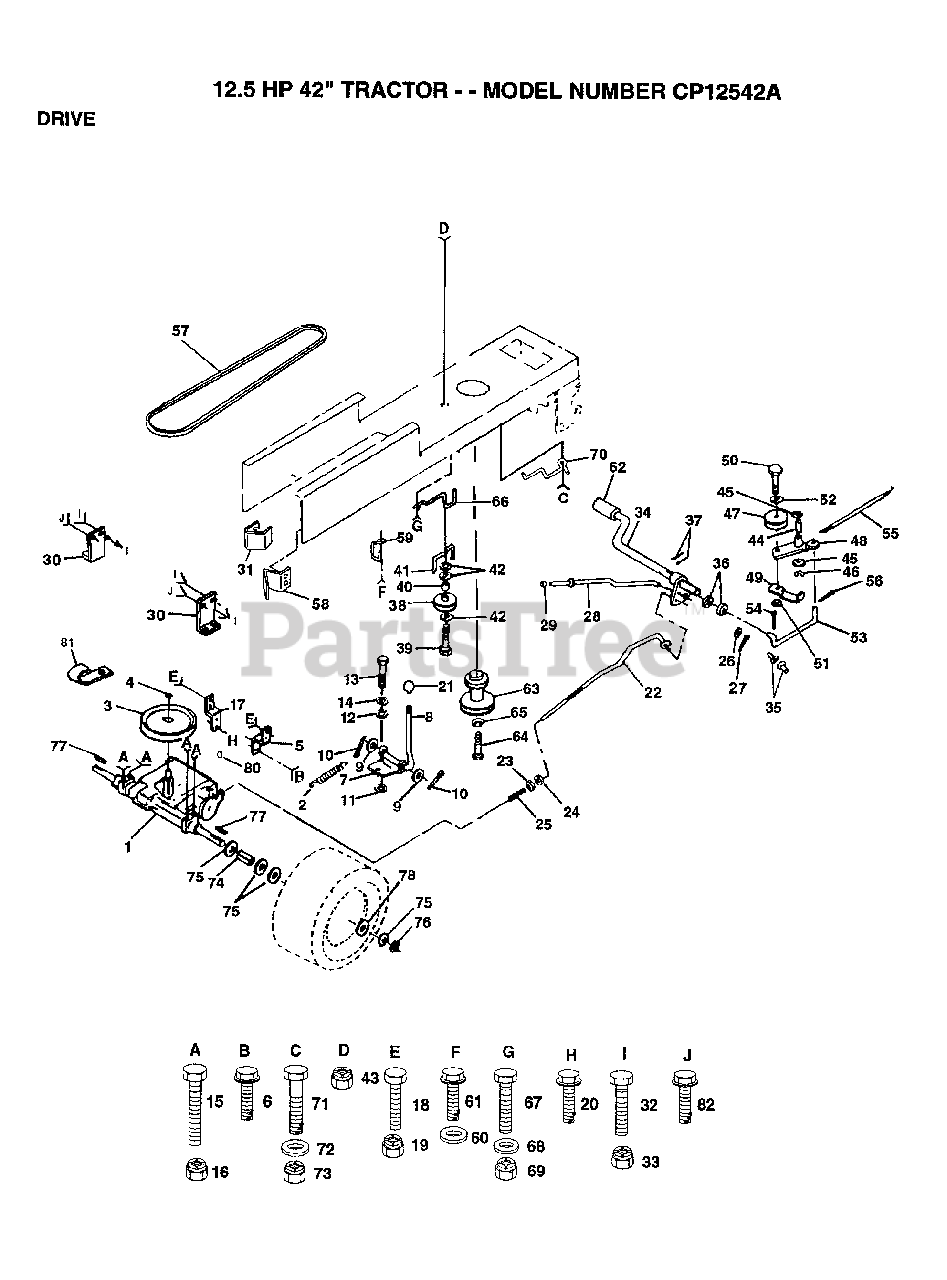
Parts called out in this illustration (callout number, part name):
1	LOCKWASHER
2	LOCKWASHER
4	DASH PLATE
7	NUT
9	SUPPORT ASS'Y
10	PLUG BUTTON T
16	LENS LT
27	DASH PANEL LH
31	WASHER PM
42	WASHER
46	J FASTENER LT
47	SCREW
48	SCREW
53	SCREW LT
56	BOLT
59	SCREW
60	SCREW HEX CRT
65	BOLT
66	FOOTREST PAD
67	SCREW
68	LOCKWASHER
69	WELDNUT
70	HOOD LATCH T
71	SCREW
72	SPACER LT
77	WASHER
79	CLIP T
84	WASHER
87	WASHER
104	WASHER
107	PIVOT BRKT LH
108	PIVOT BRKT RH
109	BOLT
110	BAFFLE HOOD VERT
111	FOAM-STRIP LT
